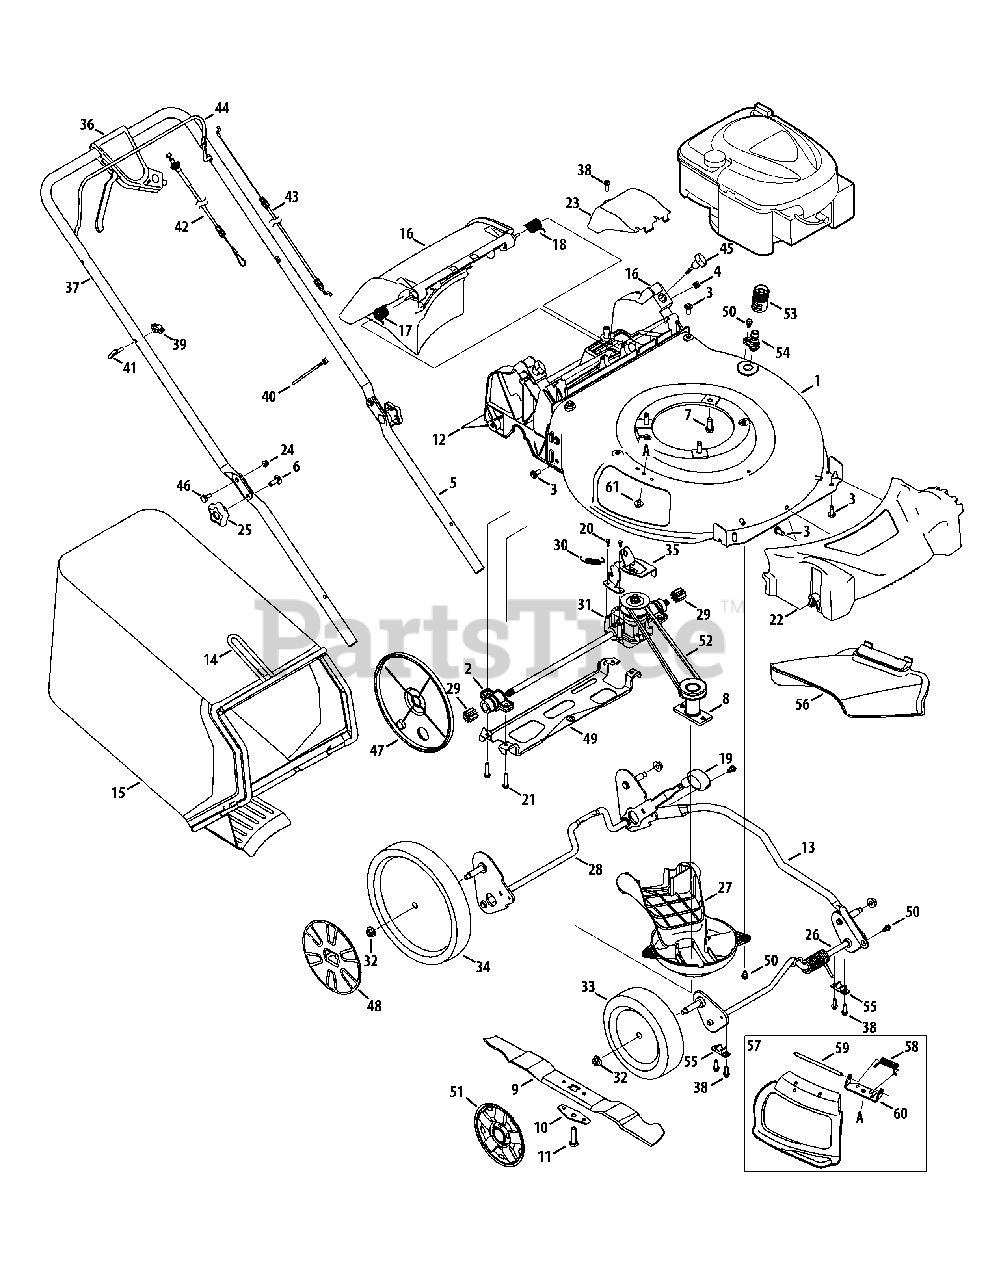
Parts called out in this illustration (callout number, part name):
1	Deck , 21"
2	Bearing Assembly
3	Screw, 5/16-14 x .750
4	Nut, Sq., 1/4-20
5	Lower Handle
6	Carriage Screw ,5/16-18
7	Screw, 3/8-16 x 1.00
8	Blade Adapter
9	Mulching Blade
10	Blade Bell Support
11	Screw, 3/8-24 x 1.50
12	Trailing Shield
13	Cross Bracket
14	Grass Catcher Frame
15	Grass Bag
16	Rear Discharge Door Assembly
17	Torsion Spring - RH
18	Torsion Spring - LH
19	Adjustment Lever Knob
20	Screw, Hex Washer, .159 x .43
21	Screw, 1/4-15 x 1.25
22	Front Cover
23	Transmission Cover
24	Nut, Flange Lock, 1/4-20
25	Wing Knob
26	Front Axle Assembly
27	Engine Baffle
28	Rear Axle Assembly
29	Spur Gear, 9T
30	Exten. Spring, 2.405
31	Transmission Assembly
32	Flange Lock Nut, 3/8-16
33	Front Wheel
34	Rear Wheel
35	Transmission Bracket
36	Control Lever Assembly
37	Upper Handle
38	Screw, 1/4-15 x .750
40	Cable Tie
41	Rope Guide
42	Variable Speed Cable
43	Control Cable
44	Blade Control
45	Wing Nut
46	Sldr. Screw, .375 x .126 x 1/4-20
47	Wheel Dust Cover
48	Hub Cap, 11"
49	Rear Support Bracket
50	Scr., Shldr., 1/4-20 x .50
51	Hubcap, 8"
52	V-Belt
53	Water Nozzle Adapter
54	Water Nozzle
55	Bushing, Lock, .505 Dia. X .62
56	Side Discharge Chute
57	Mulch Plug (Incl. 58-60)
58	Torsion Spring
59	Hinge Pin
60	Chute Deflector Bracket
61	Screw, 1/4-20 x .500
